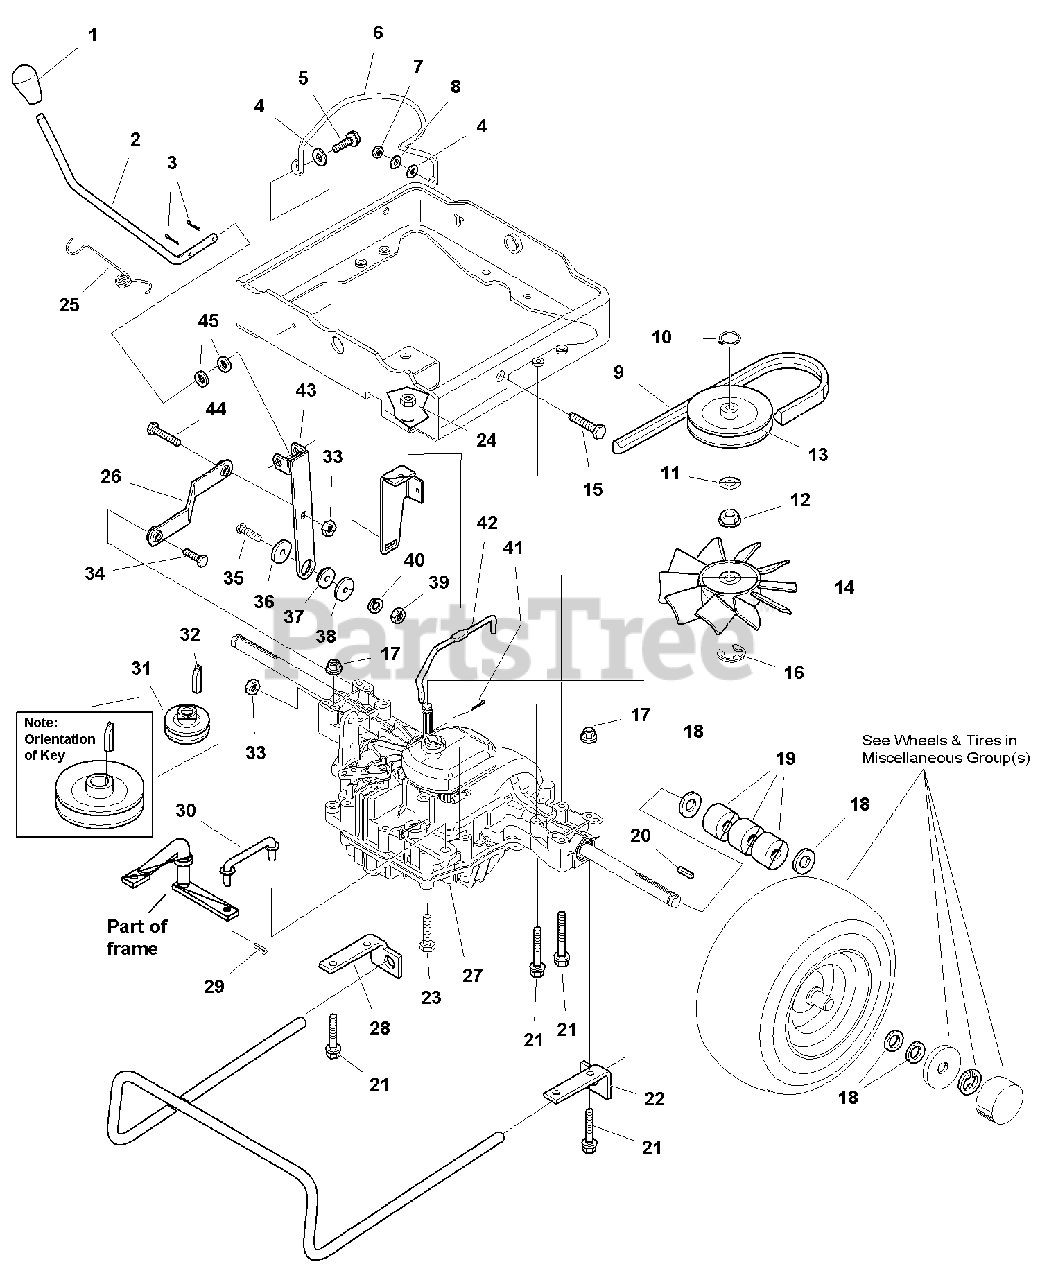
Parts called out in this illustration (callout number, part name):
3	PIN, Cotter
5	SCREW, Hex Washer Head Taptite, 5/16-18 x 3/4
7	NUT, Hex 5/16-18
8	LOCKWASHER, 5/16
12	SPLINE COLLAR
14	FAN
15	CAPSCREW, Hex Head, 5/16-18 x 1
16	"E" RING
17	NUT, Hex Head Whiz Lock, 5/16-18
20	KEY
21	CAPSCREW, Hex Head Taptite, 5/16-18 x 2-1/2
22	ANCHOR, Torsion Bar LH
23	CAPSCREW, Hex Head Flange Whizlock, 5/16-18 x 1-3/4
24	NUT, Hex Flange Whizlock, 5/16-18
26	LINK, Transmission
27	TRANSMISSION ASSEMBLY
28	ANCHOR, Torsion Bar RH
29	PIN, Cotter
31	PULLEY & HUB ASSEMBLY
32	KEY, Hi-Pro
33	NUT, Hex Two Way Lock, 5/16-18
34	CAPSCREW, Hex Head, 5/16-18 x 1-1/4
35	CARRIAGE BOLT, 3/8-16 x 1-1/4
36	WASHER
39	NUT, Hex, 3/8-16
40	LOCKWASHER, 3/8
41	PIN, Cotter
43	LEVER & CLEVIS ASSEMBLY
44	CARRIAGE BOLT, 5/16-18 x 1
